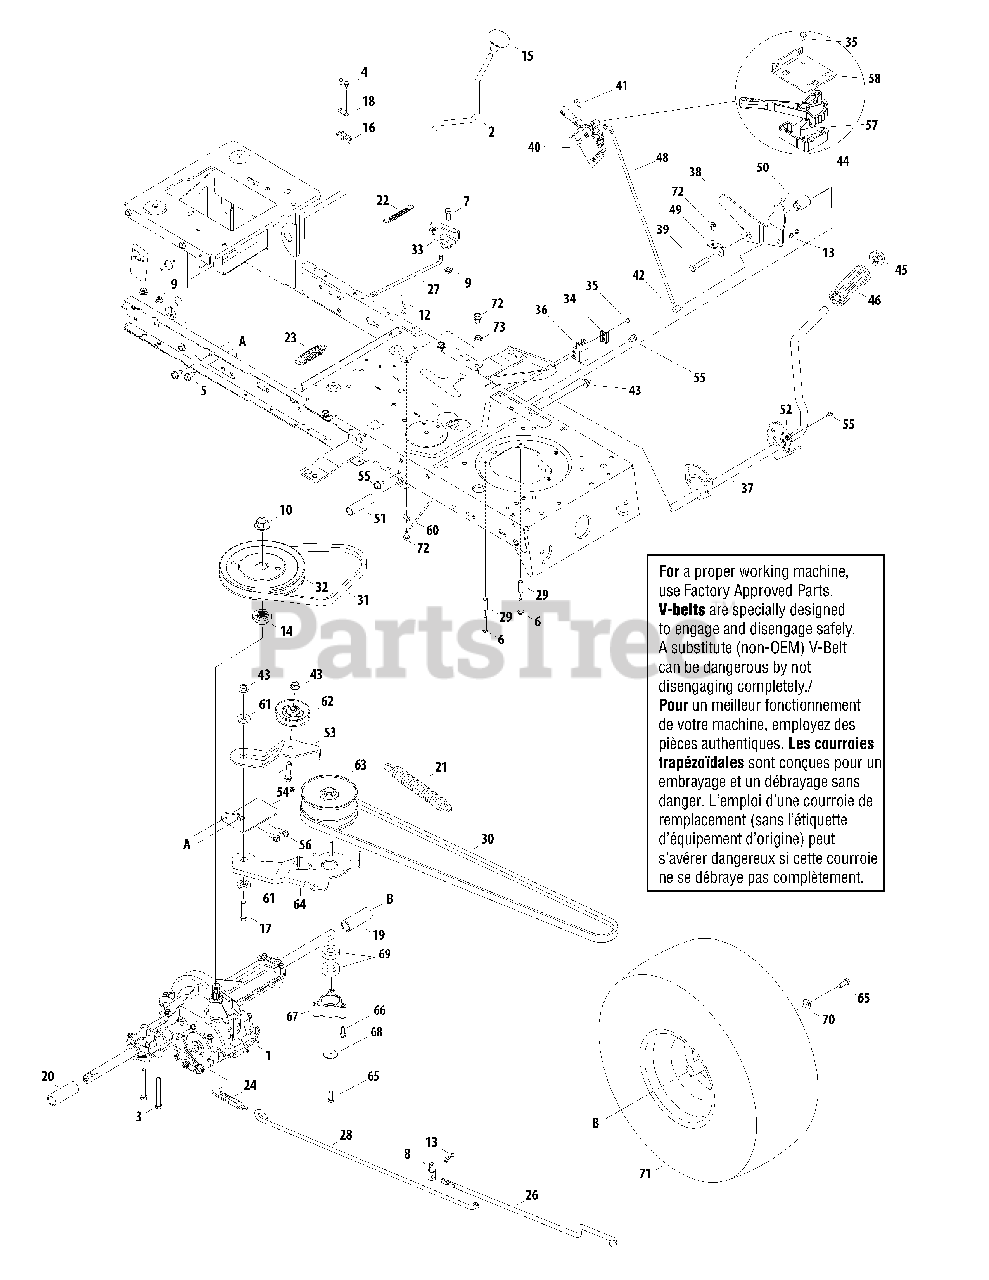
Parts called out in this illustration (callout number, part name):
1	Transmission Asm
2	Shift Lever Asm
3	Hex Screw 5/16-18 x 2.75
4	Hex Wash HD AB S-Tapp Screw #8-.50
5	S-Tapp Screw 5/16-18 x .75
6	Hex Bolt 1/4-20 x 1.25
7	Hex Bolt 5/16-18 x .75" Lg. Gr. 5
8	Ferrule
9	Flange Locknut 5/16-18 Gr. F, Nylon
10	Flange Nut
11	Cotter Pin 3/32 dia x 1.00 Lg.
12	Cotter Pin
13	Bow Tie Cotter Pin
14	Pulley Hub 5/8" Spline
15	Shift Knob
16	Short Spring Switch
17	Screw, 3/8-16 x 1.75
18	Insulator Nut Plate
19	Sleeve, .758 x .821 x 3.3125
20	Sleeve, .758 x .821 x 2.4375
21	Spring, Extension, .94 OD x 6.75
22	Spring, Extension
23	Spring, Extension, .80 OD x 3.28
24	Ext. Spring .59 OD x 4.00 Lg.
25	Flat Washer .344 ID x .625 OD x .063
26	Control Rod, Variable Speed
27	Shift Rod (38"/42" deck)
27	Shift Rod (46" deck)
28	Brake Rod
29	Spacer .260 x .375 x 1.030 Lg.
31	Belt
32	Pulley, V-Type, 7.25 dia.
33	Shift Bracket, Adjustable
34	Switch Plate
35	Hex AB-Tap Screw #10 X .50" Lg.
36	Interlock Switch
38	Latch Asm, Engagement (RMC)
39	Hex Screw 3/8-16 x 2.0 Gr. 5
40	6 Speed Shift Control Ass'y
40	7 Speed Shift Control Ass'y
41	Tap Screw 1/4-20 x .50
42	Adjustment Ferrule
43	Flange Lock-Nut 3/8-16 Gr. F Nylon
44	Control Cover
45	Push Cap 5/8" Dia Rod
46	Foot Pad
48	Speed Selecter Control Rod
50	Flange Spacer .390 x .671 x 1.095
51	Spacer .630 ID
53	Idler Bracket
54	Transmission Torque Bracket
55	Self-tapping Screw 5/16-18 x .625
56	Hex Wash. Hd. Screw. 5/16-18 x .75 Lg.
57	Shift Lever Spring
58	Control Bracket
60	Belt Keeper Rod
61	Shoulder Spacer
62	Flat Idler
63	Variable Speed Pulley Asm 4.75 OD
64	Variable Speed Bracket Asm
65	Hex L-Screw 5/16-24 x 0.75 Gr. 5
66	Hex Screww 1/4-20 x 1.5
67	Bearing Cup
68	Flat Washer .22 ID x 1.25
69	Ball Bearing 17 x 40 x 12
70	Cupped Washer .345 ID x .88 OD x .060
72	Hex Wash S-Tapp Screw 1/4-20 x .50
73	Lockwasher 1/4"
